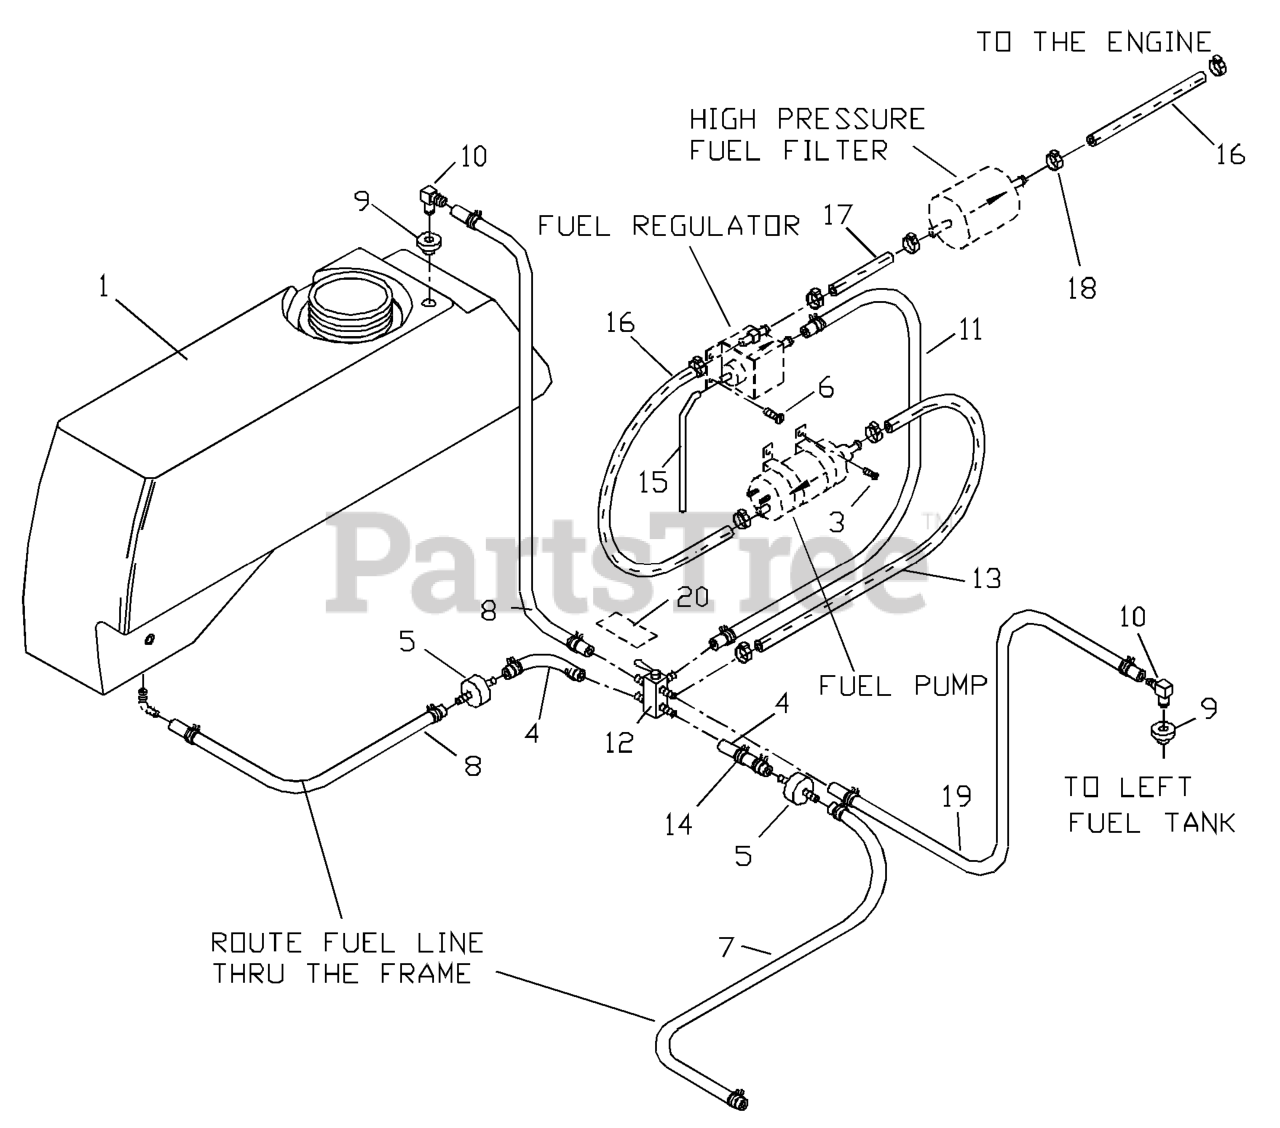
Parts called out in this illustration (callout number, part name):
1	FUEL TANK DIESEL RT
2	FUEL TANK DIESEL LT
3	SCREW #10 X 1/2 SELF TAPPING
4	GAS LINE 3 1/2"
5	FUEL FILTER
6	HEX CAP SCREW 1/4
7	FUEL LINE 29.5"
8	FUEL LINE 18"
9	RUBBER GROMMET
11	FUEL LINE 24"
12	FUEL VALVE
13	EFI HOSE - 18"
14	HOSE CLAMP
16	EFI HOSE - 8"
17	EFI HOSE - 4"
19	FUEL LINE 34"
20	FUEL VALVE DECAL
